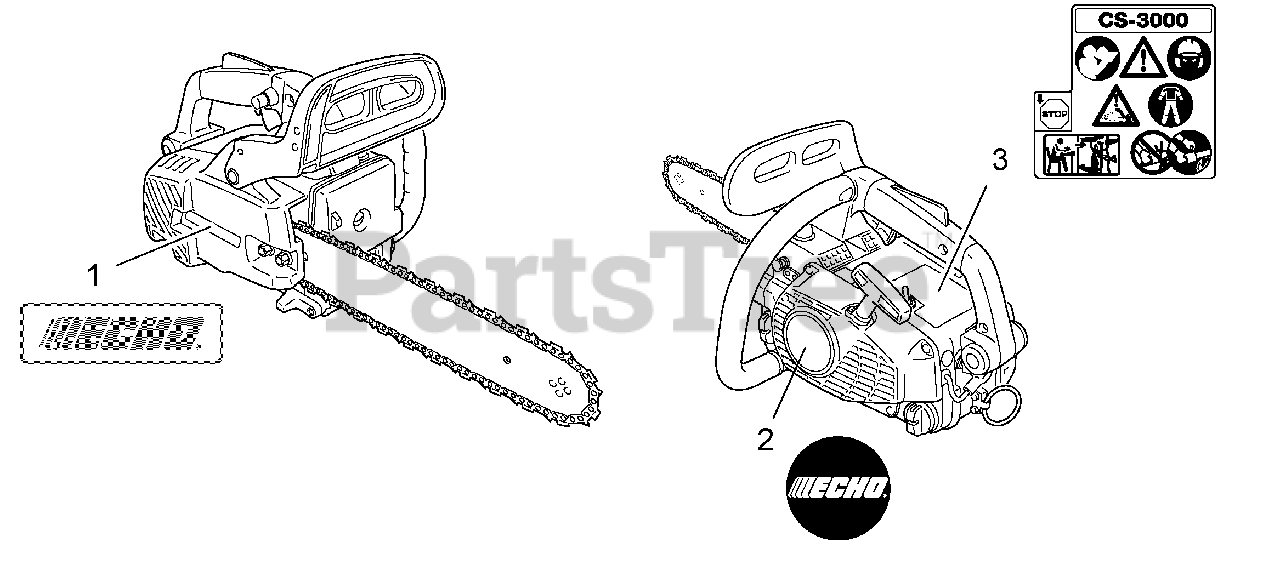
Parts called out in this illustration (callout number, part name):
1	LABEL, ECHO
2	LABEL, ECHO
3	LABEL, CS-3000 / CAUTION
